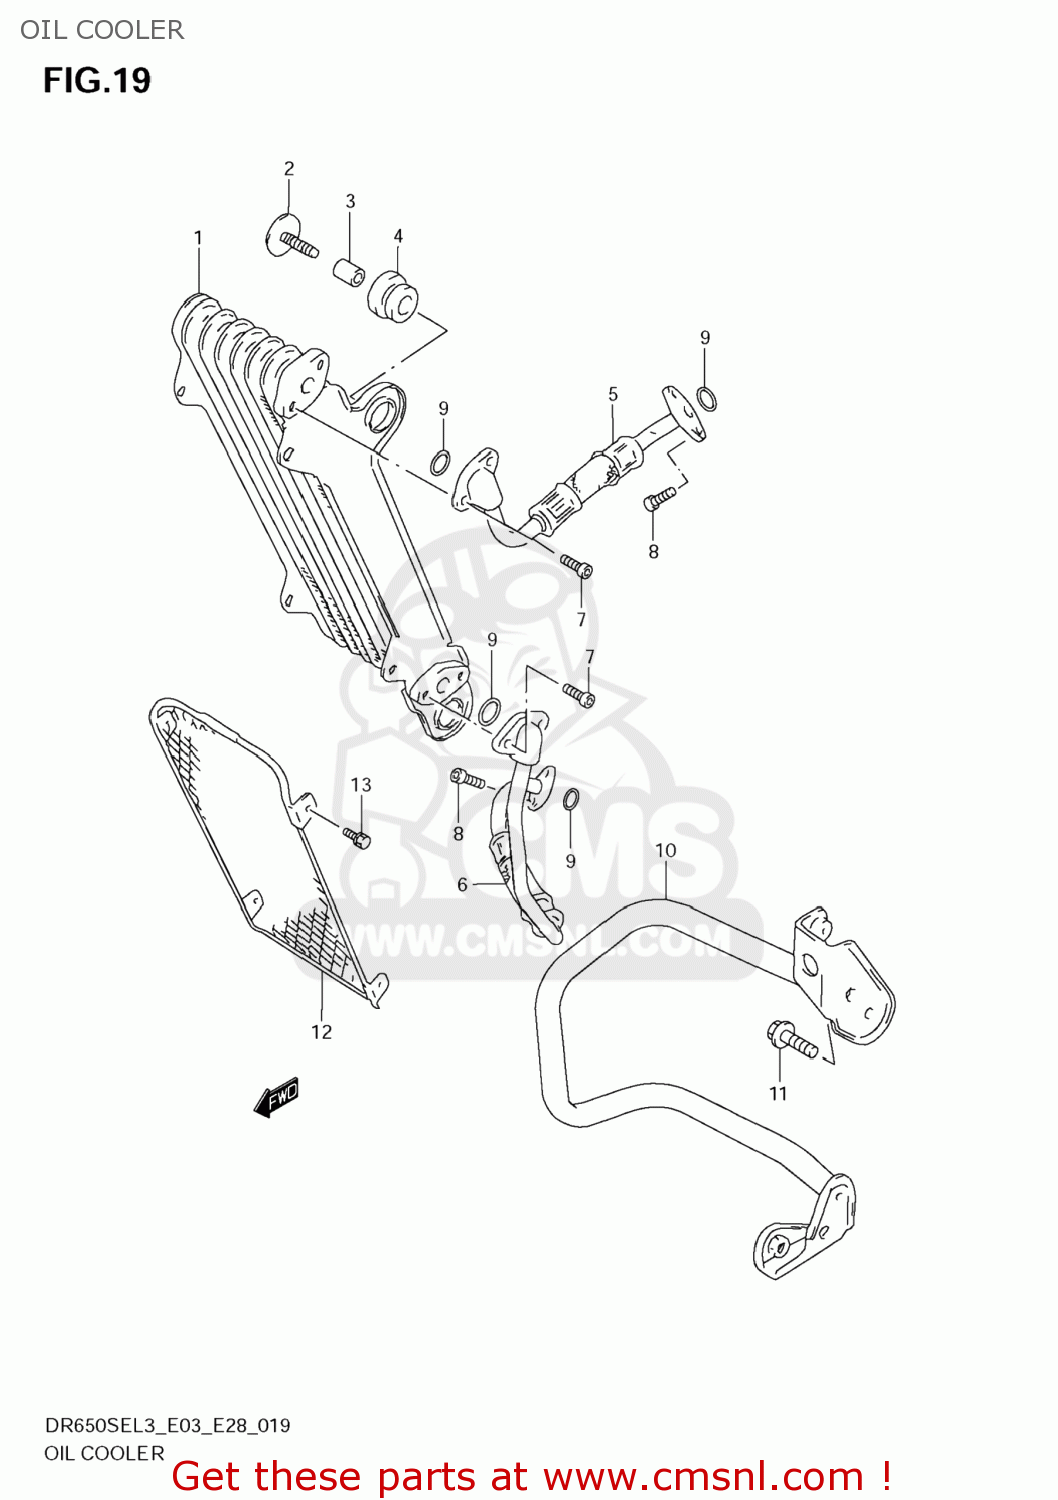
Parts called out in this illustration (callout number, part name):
1	COOLER ASSY,OIL
2	BOLT(8X28)
3	SPACER(8.5X12X17)
4	CUSHION,OIL COOLER
5	HOSE,OIL COOLER UPR
6	HOSE,OIL COOLER LWR
7	BOLT
8	BOLT
9	O RING(D:2.4,ID:11.8)
10	GUARD,OIL COOLER
11	BOLT
12	BUMPER,OIL COOLER
13	SCREW
